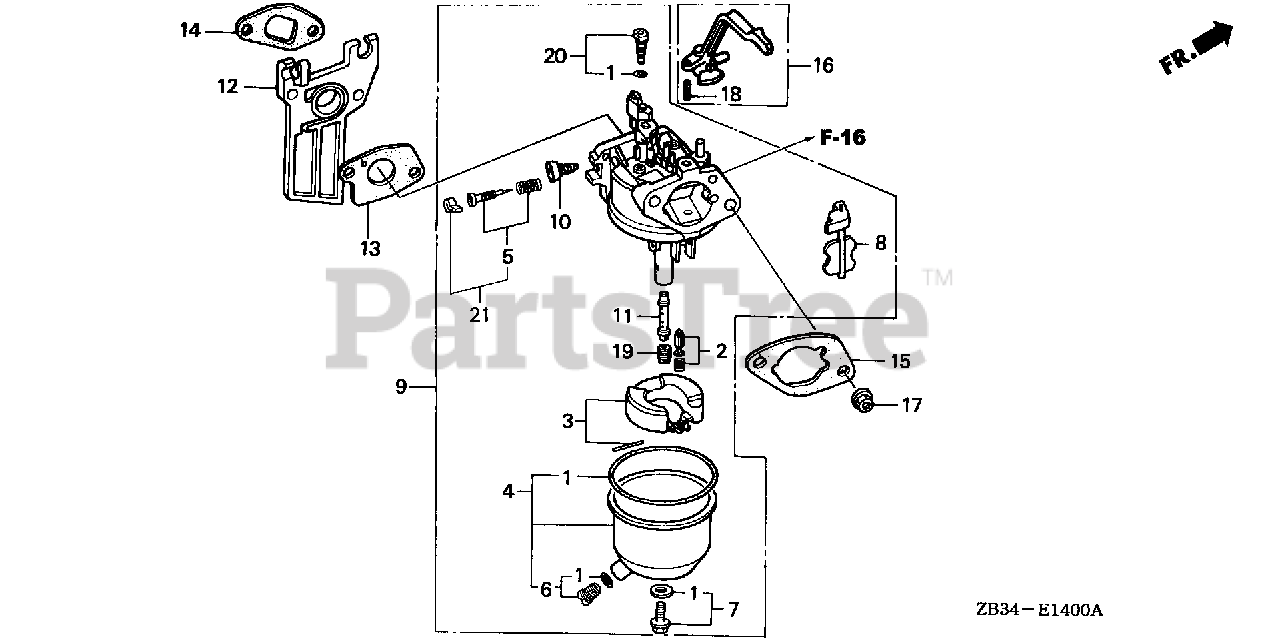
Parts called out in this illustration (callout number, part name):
1	GASKET SET (CARBURETOR NO.)
2	VALVE SET, FLOAT (SEAT NOT INCLUDED)
4	CHAMBER SET, FLOAT (CARBURETOR NO.)
4	CHAMBER SET, FLOAT
6	SCREW SET, DRAIN (CARBURETOR NO.)
7	SCREW SET
9	CARBURETOR ASSY. (BE67A B)
10	SCREW, THROTTLE STOP
11	NOZZLE, MAIN
12	INSULATOR, CARBURETOR
13	GASKET, CARBURETOR
14	GASKET, INSULATOR
15	GASKET, AIR CLEANER
16	LEVER, CHOKE
17	NUT, FLANGE (6MM)
18	PIN, SPRING (2X12)
19	JET, MAIN (#72)
19	JET, MAIN (#75)
19	JET, MAIN (#70)
20	JET SET, PILOT (#35)
21	SCREW SET, PILOT
